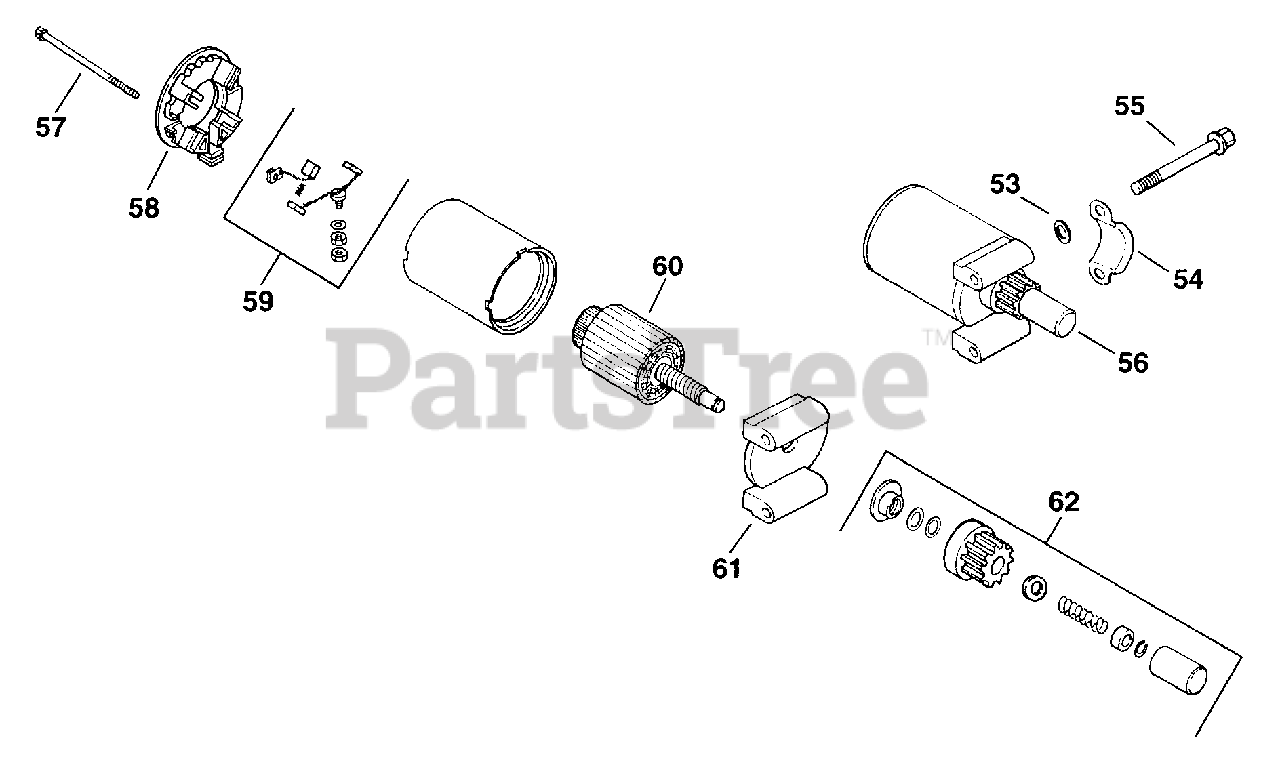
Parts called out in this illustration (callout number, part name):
53	WASHER, FLAT 5.5 MM
54	COVER, PINION
55	SCREW - USE M-839070
57	SCREW - (#DSC)
58	COMMUTATOR, END CAP
59	KIT, BRUSH & SPRING - DISCONTINUED
60	ARMATURE ASSY - DISCONTINUED
62	KIT, DRIVE
